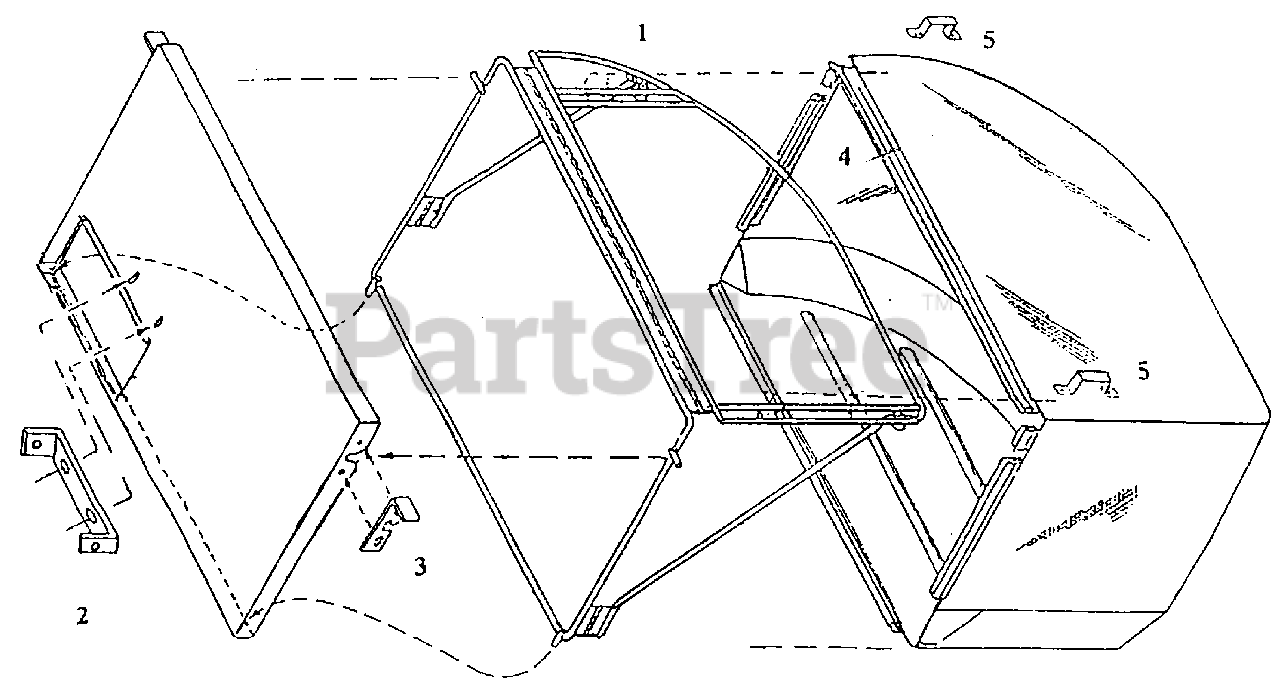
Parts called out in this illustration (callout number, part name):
1	Frame Assembly
2	Bolt on Bracket
3	Bag Release Latch
4	Cloth Bag
5	Handle
